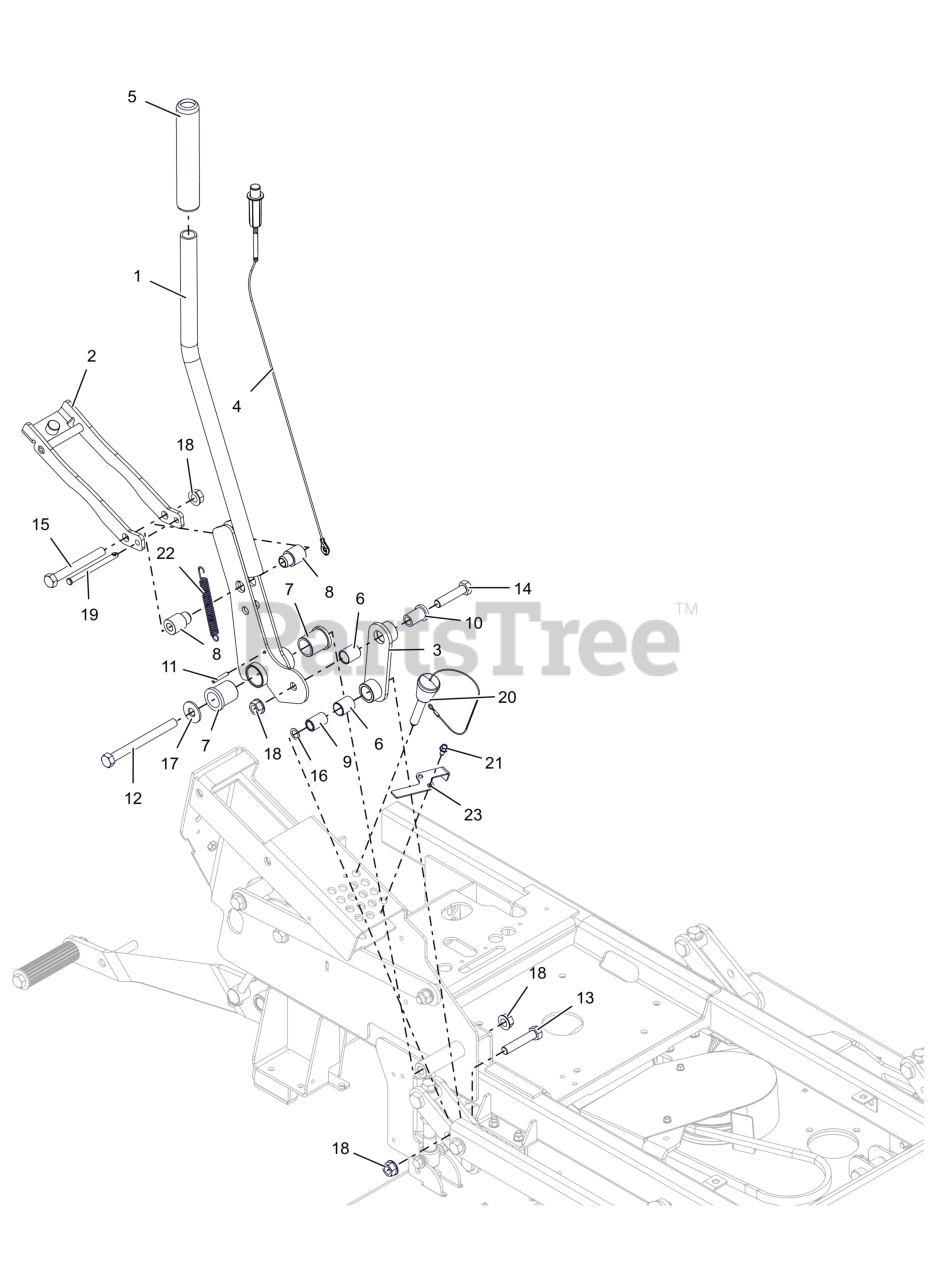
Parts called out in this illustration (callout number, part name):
1	WLDMT, HOC LEVER (BLACK)
2	WLDMT, HOC BRACKET (BLACK)
3	WLDMT, HOC LEVER LINK (BLACK)
4	CABLE, HOC PUSH CONTROL
5	GRIP, DECK LIFT
6	BRG- .750 X .875 X 1.000
7	BSHG-FLG 1.00X1.25X1.50X1.50
8	BSHG-FLG.515X.750X1.544X1.000
9	SPCR, SLV .532 X .750 X 1.150
10	BSHG-FLG .515X.746X1.290X1.000
11	PIN-ROLL .188X1.25
12	BLT,HEX .50-13X5.50 G5 ZCC
13	BLT, HEX .50-13X2.50 G5 ZCC
14	BLT, HEX .50-13X2.25 G5 ZCC
15	BLT, HEX .50-13X4.25 G5 ZCC
16	WASHER, .500X.750X.020 THRUST
17	WSHR,FLT .563X1.375X.109 ZCC
18	NUT-LK-CTR-FLG .500-13 GG ZCC
19	PIN-SLIC .3125 X 4.015 X 3.625
20	PIN- MAGNETIC .50X2.70
21	SCR-TAP .25-20X.50 HWH ZCC
22	SPRING,EXT,.061X.50X3.0
23	BLOCK, HOC SELECTION (BLACK)
